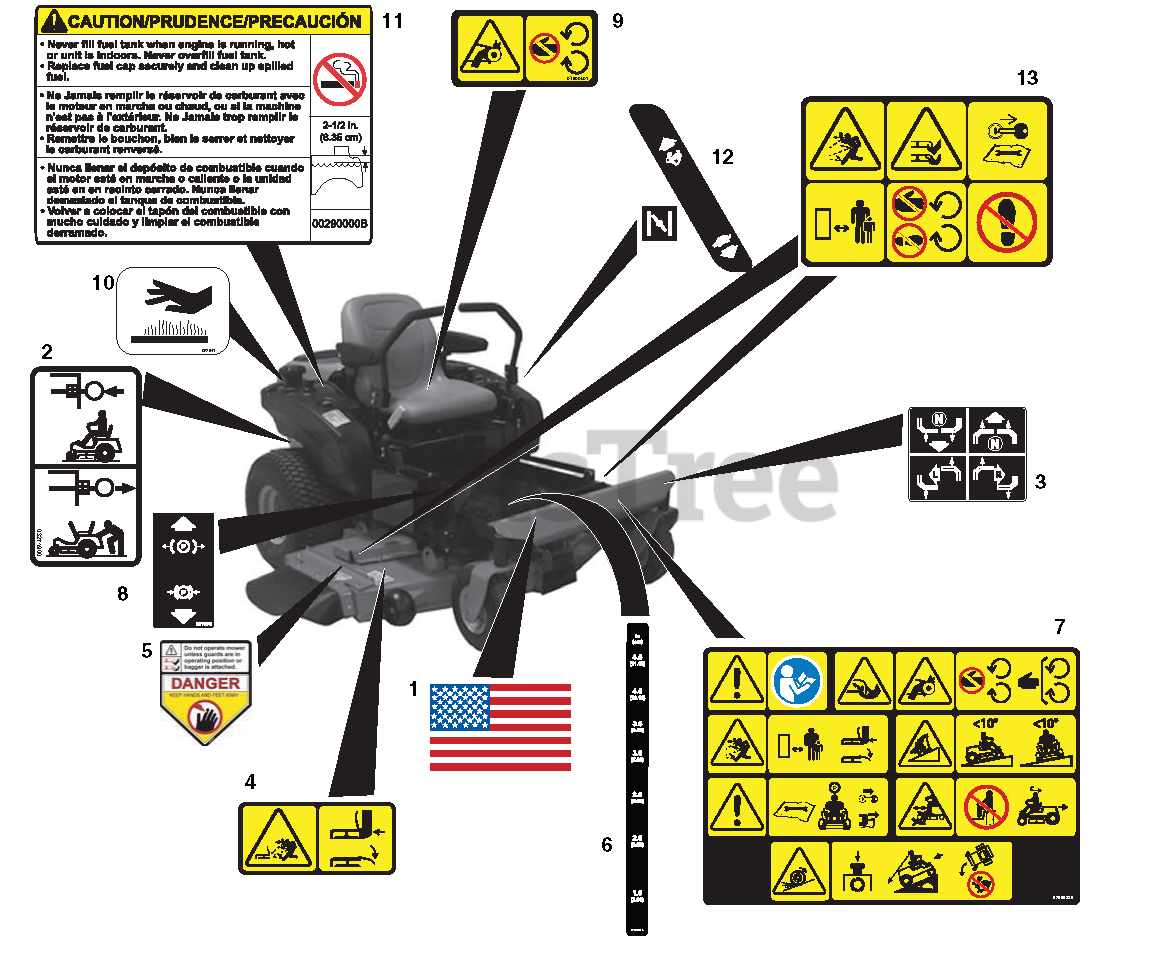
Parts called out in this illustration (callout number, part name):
1	DECAL, AMERICAN FLAG
2	DECAL, TRANSMISSION DISCONNECT
3	DECAL, INSTRUCTIONAL-STEERING
4	DECAL, SAFETY - DECK GUARDING
5	DECAL, DANGER
6	DECAL, CUT HEIGHT XL
7	DECAL, SAFETY - MAIN
8	DECAL, PARKING BRAKE LEVER
9	DECAL, SAFETY - GUARDING
10	DECAL, HOT SURFACE
11	DECAL,FUEL WARNING
12	DECAL, SPEED CONTROL
13	DECAL, SAFETY - MOWER DECK
